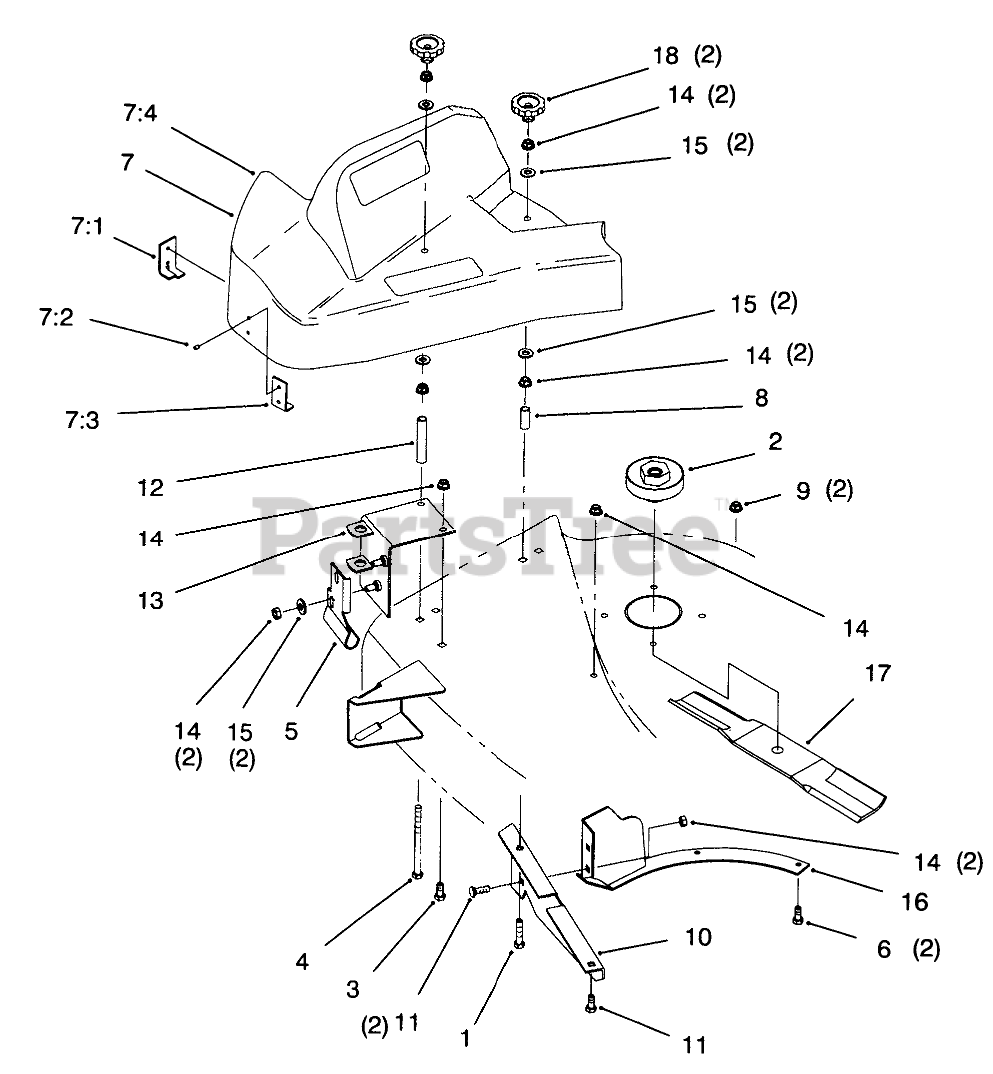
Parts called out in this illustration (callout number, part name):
1	SCREW-CARR
2	PULLEY
3	SCREW-CARR
4	SCREW-CARR
5	BRACKET - PIVOT BLACK
6	SCREW-HH
7	BELT SHIELD ASM
7:1	BRACKET-SUPPORT, SHIELD
7:2	RIVET-POP
7:3	BRACKET-SUPPORT, SHIELD
7:4	Shield-Belt
8	TUBE-LATCH
9	NUT-LOCK, NI
10	Baffle-Rear
11	SCREW-CARR
12	TUBE-SPACER
13	WA - PIVOT BRACKET
14	NUT-LOCK, NI
15	WASHER-PLAIN
16	BAGGING RING RH-WELDED B
17	Blade
